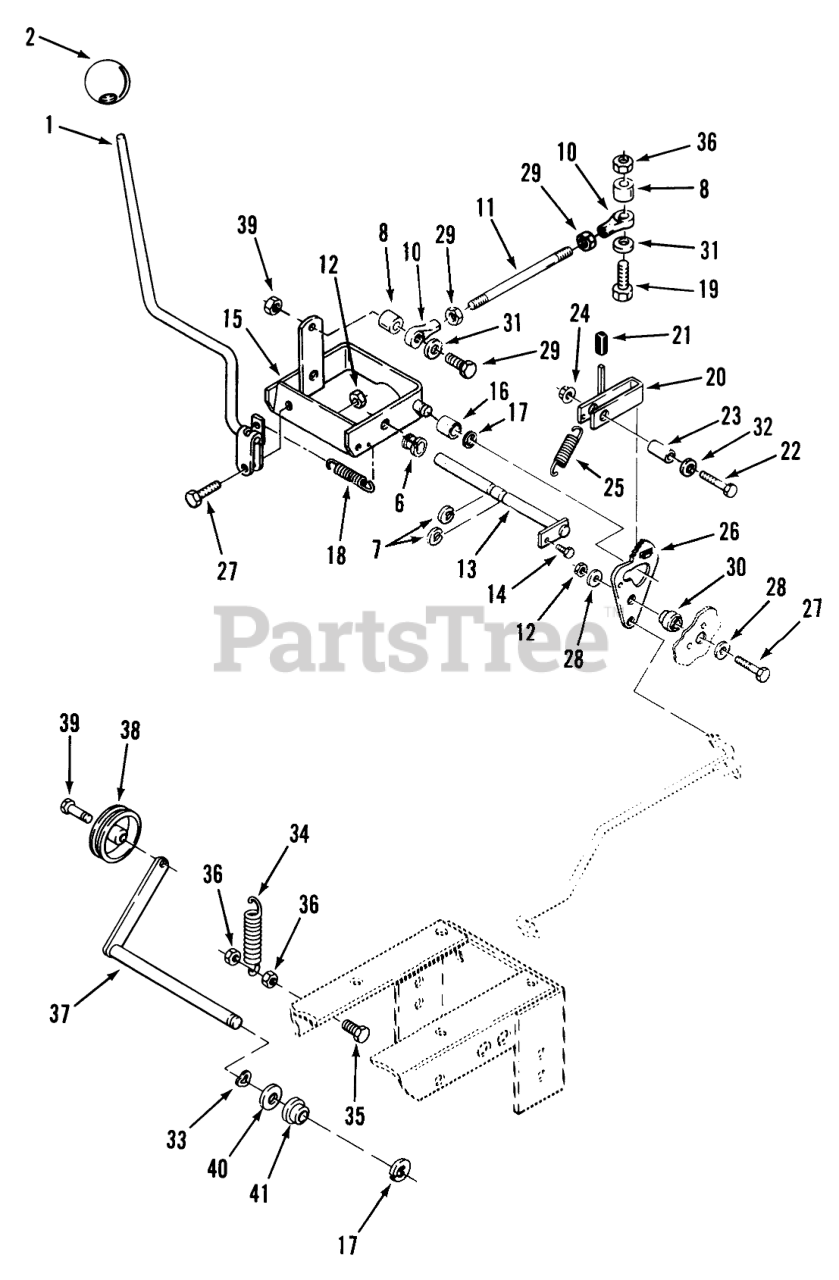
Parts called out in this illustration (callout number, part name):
1	ASS'Y-ARM CONTROL *B
6	BUSHING-NYLINER
8	BEARING CAM ROLLER
10	ASSY ROD END
11	ROD-CONTROL
14	SCREW
16	BEARING-CAM RETURN
18	SPRING
21	VALVE LEVER GRIP
23	SPACER
33	WASHER-WAVE
34	SPRING-EXTENSION
38	PULLEY-IDLER
39	BOLT-SPECIAL HEX
41	BUSHING-FLANGED
